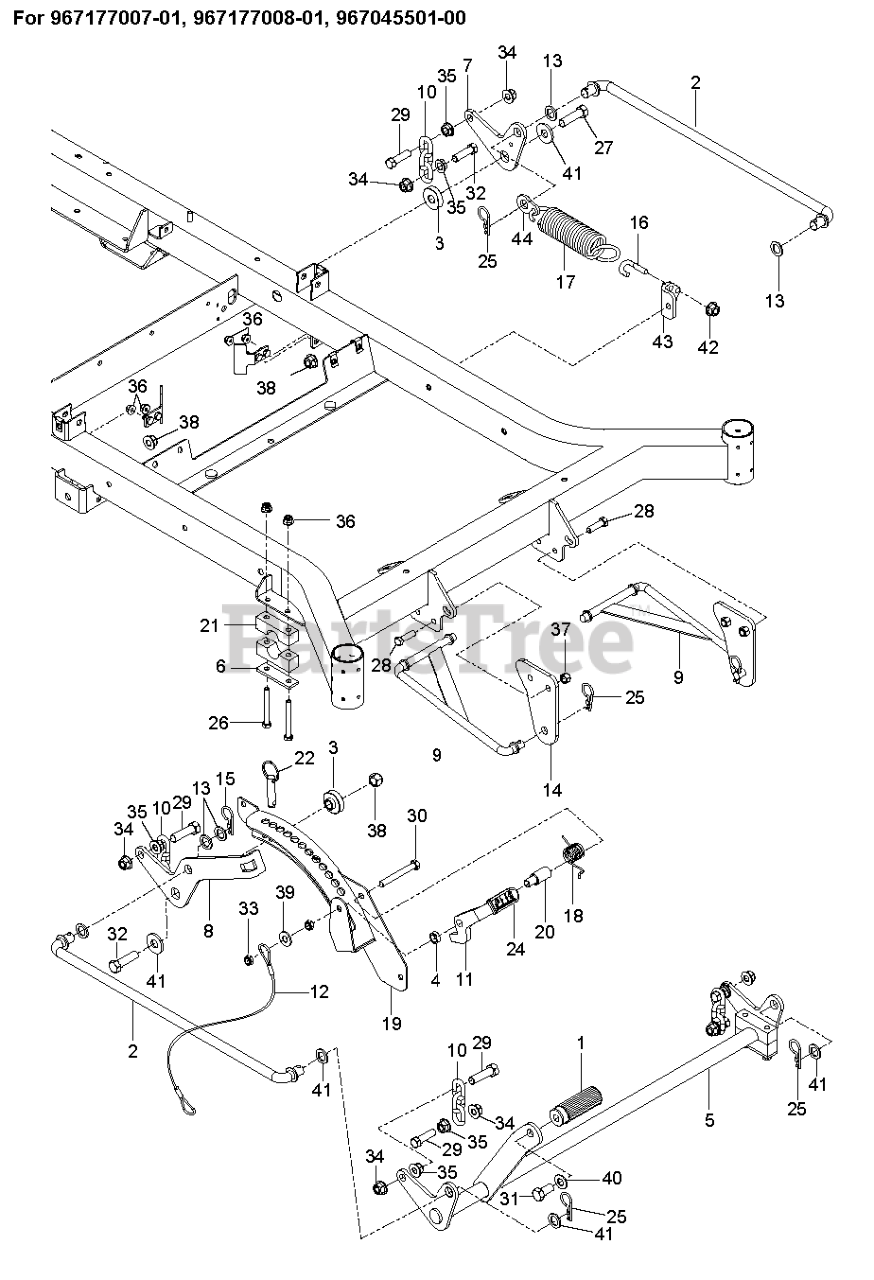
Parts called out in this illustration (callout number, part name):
1	PEDAL, DECK HEIGHT
2	CROSS LINK
3	SPACER.IDLER.METAL.POWDER
4	SPACER, .3
5	LIFT.PNT.MZ.DECK.WELD.E-DIP
6	REINFORCEMENT.PLATEX431
7	BELLCRANK, RR, LIFT
8	BELLCRANK, RR, RT
9	STRUT LINKAGE
10	LIFT CHAIN - 3 LINK
11	LATCH, TRANSPORT
13	WASHER LT
13	BUSHING
14	MOUNT, STRUT
15	PIN.COTTER.7/16.BOW TI.
17	SPRING
18	SPRING, TORSION
19	HEIGHT, ADJUST, DECK
20	PIVOT, LATCH, TRANSPORT
21	PILLOW BLOCK
22	PIN, 1/2 X 1 1/2, DETENT RING
24	GRIP, TRANSPORT-RELEASE
25	PIN, COTTER 1 3/4
26	BOLT HEX
26	HCS 5/16C X 2-3/4
27	HCS 1/2-13 X 1 3/4 GR 8
28	HCS 3/8C X 1 1/4 GR5
29	HCS 7/16C X 1 1/2
30	BOLT.HEX.FIN.3/8-16 X 3.GR5
31	HHCS 1/2-13 X 1
32	HCS 7/16 - 14 X 1 3/4
33	NUT HEX 3/8-16 NYLON, THIN
34	NUT 7/16-14 HEX WHIZ LK
35	NUT 7/16C WHIZ
36	5/16-18 NYLOC FLANGE NUT
37	NUT 3/8-16 NYLOC
38	NUT.LK.W/WSH.1/2.
38	NUT 1/2-13 HEX NYLOC ZD
39	RP WASHER 3/8 FLAT
40	CONTACT BELLSPR 1/2
41	WASHER.9/16 X 1 3/8 X 12 GA.
41	WASH USS FLAT 1/2
42	5/16-18 NYLOC FLANGE NUT
43	MOUNT, SPRING
44	TAB, SPRING
